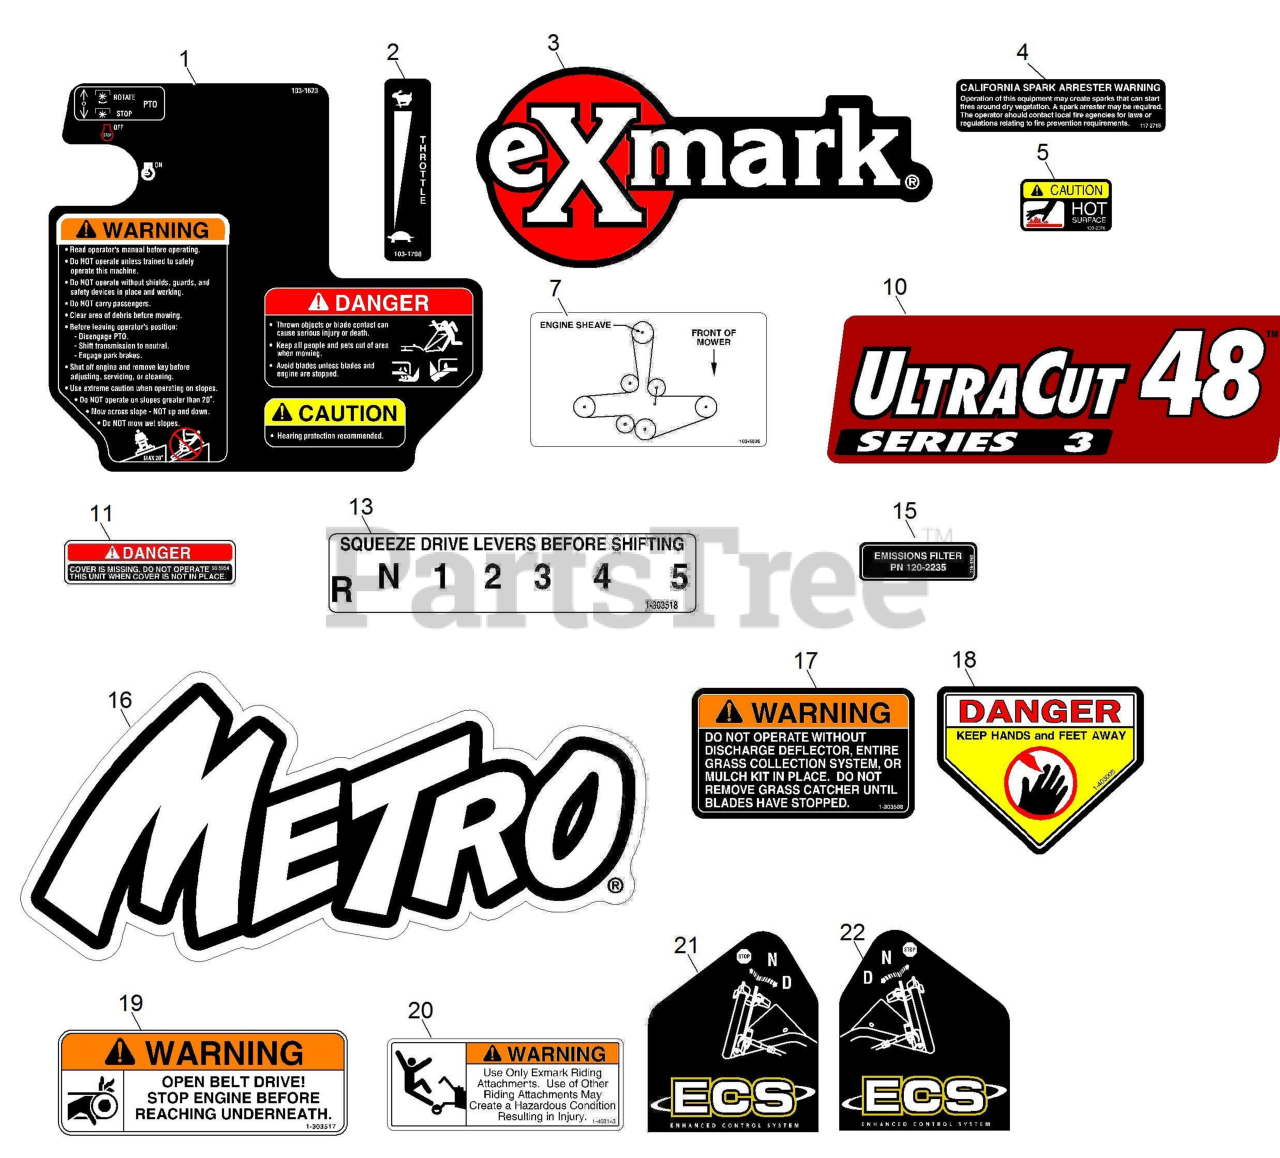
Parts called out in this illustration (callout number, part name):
1	DECAL,METRO ECS CONSOLE
2	DECAL,THROTTLE ONLY
3	DECAL,EXMARK LOGO
4	DECAL-ARRESTER, SPARK
5	DECAL-CAUTION
7	DECAL,BELT ROUTING
10	DECAL-ULTRACUT 48 SERIES
11	DECAL-COVER, MISSING
13	DECAL,SHIFTER
15	DECAL-FILTER, EMISSIONS
16	DECAL,METRO MODEL
17	DECAL-WARNING, DISCHARGE
18	DECAL-DANGER
19	DECAL,BELT DRIVE
20	DECAL,SULKY WARNING
21	DECAL,RH ECS INSTRUCTION
22	DECAL,LH ECS INSTRUCTION
